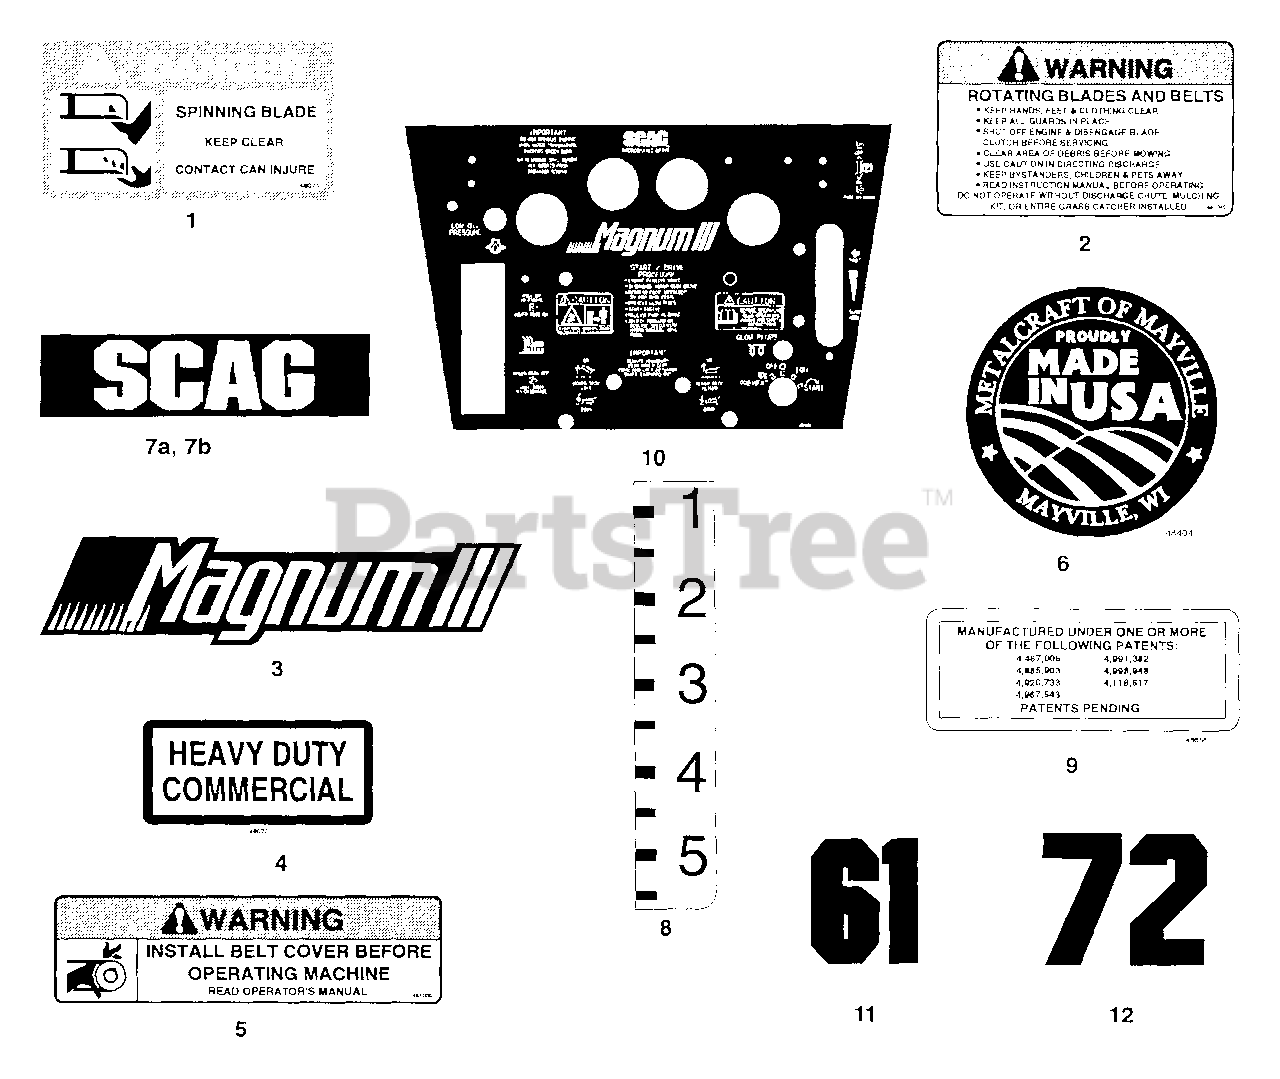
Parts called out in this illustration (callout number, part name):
1	Decal, Danger - Spinning Blades
2	Decal, Warning - Rotating Blades
3	Decal, Magnum III
4	Decal, Heavy Duty Commercial
5	Decal, Warning - Belt Cover
6	Decal, Metalcraft - Made In USA
7A	Decal, Scag Logo - 12" x 4.23 (Hood)
7B	Decal, Scag Logo - 8.5" x 2" (Seat Back)
8	Decal, Cutting Height
9	Decal, Patent
10	Decal, Instrument Panel
11	Decal, 61
12	Decal, 72
